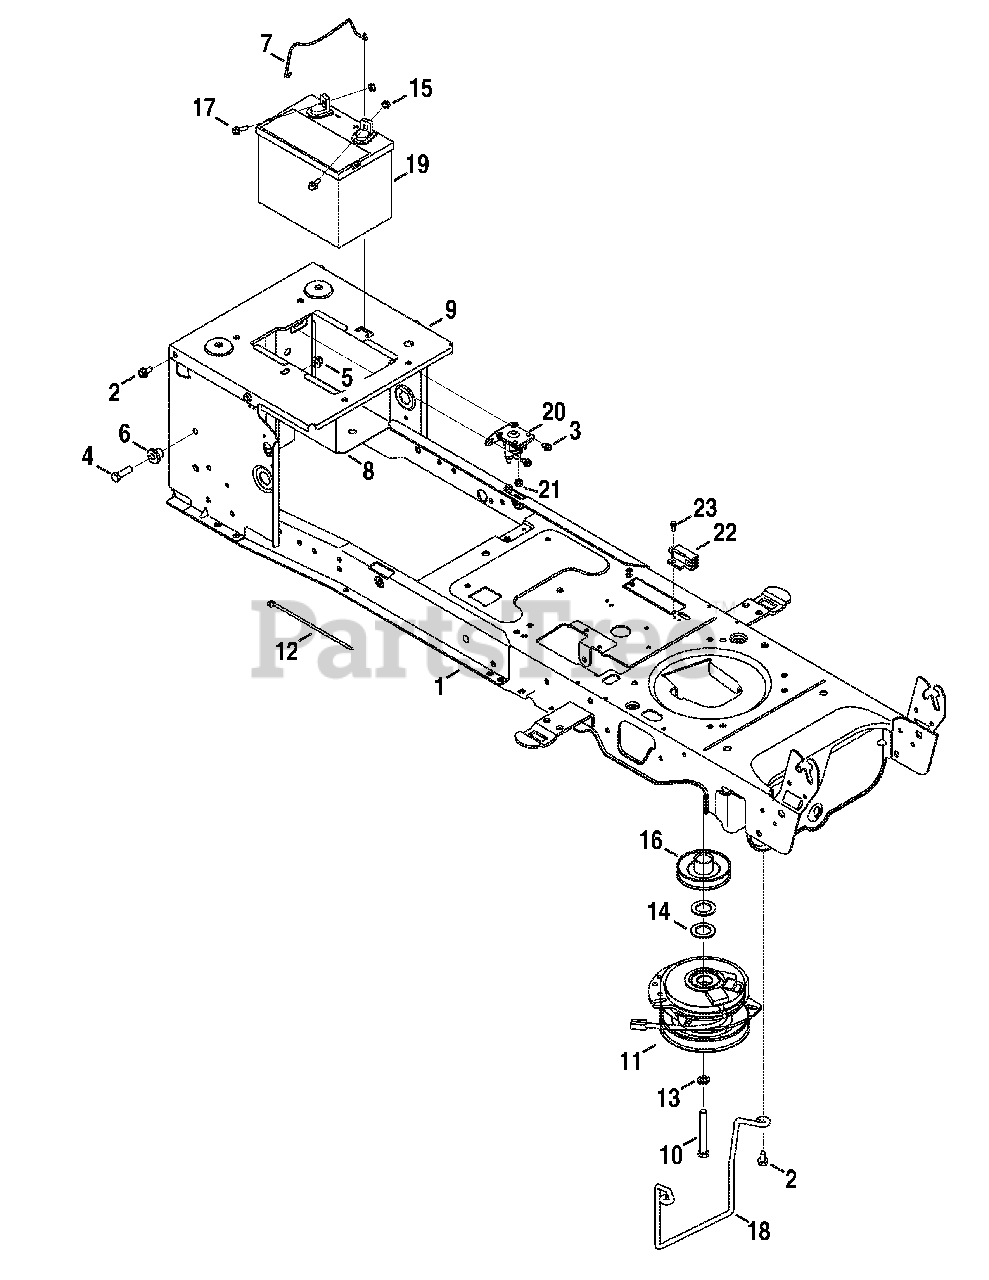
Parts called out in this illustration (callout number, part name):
1	Frame
2	Taptite Screw, Indented Washer, 5/16-18:.750
3	Taptite Screw, Indented Washer, 1/4-20:0.500
4	Hex Head Screw, 3/8-16:1.25
5	Flangelock Nut, 3/8-16
6	Shoulder Spacer, .38 X 1.0 X .70
7	Battery Holder Rod
8	Battery Tray
9	Seat Frame Bracket
10	Hex Head Screw, 7/16-20:3.50
11	Electric PTO Clutch
12	Cable Tie, 3/16 x .05 x 7.4
13	Lock Washer, 7/16
14	Flat Washer, 1.031 x 1.620 x .095
15	Sems Nut, 1/4-20
16	Electric PTO Engine Pulley
17	Hex Head Flange, 1/4-20 .75
18	Belt Guard
19	Battery
20	Solenoid, 12 V
21	Flangelock Nut, 1/4-20
22	Interlock Switch
23	Shoulder Screw, #10-32:.500
